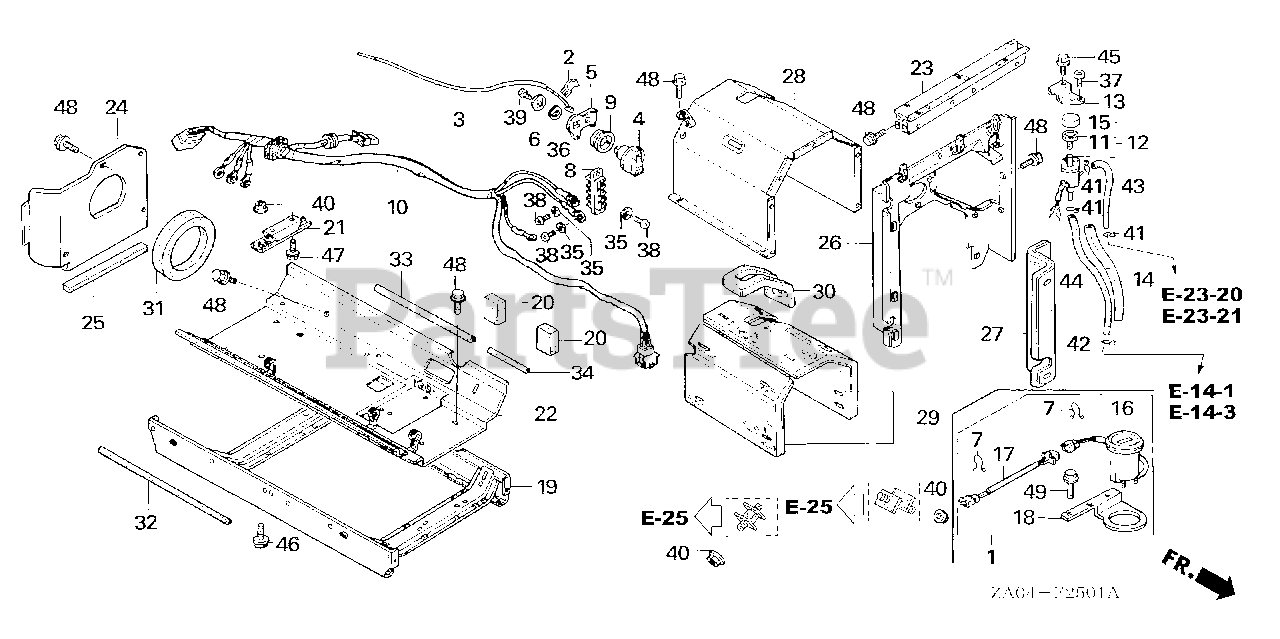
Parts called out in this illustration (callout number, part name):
1	METER KIT, HOUR
2	HOLDER, CONTROL CABLE
3	CABLE, CHOKE
4	KNOB, CHOKE CONTROL
5	ARM, CHOKE
6	WASHER, SPECIAL
7	CLIP, PURSE LOCK
8	TERMINAL, A.C. OUT
9	BUSH, PETCOCK SHAFT
10	WIRE HARNESS ASSY., A.C. (NOT AVAILABLE)
11	FILTER ASSY., SOLENOID VALVE
12	VALVE ASSY., CONTROL
13	STAY, IDLE CONTROL
14	PROTECTOR, TUBE (9X210)
15	CAP, AIR FILTER
16	METER ASSY., HOUR
17	CORD, HOUR METER CONNECTING
18	BRACKET, HOUR METER
19	FRAME (LOWER)
20	SEAL, FRAME (LOWER)
21	RUBBER, GENERATOR MOUNTING
22	COVER (LOWER)
23	BEAM, CENTER
24	COVER, RR. GENERATOR
25	SEAL, RR. GENERATOR COVER
27	INSULATOR, SEPARATOR
28	COVER, GENERATOR
29	INSULATOR, GENERATOR COVER
30	SEAL A, GENERATOR COVER
31	SEAL, GENERATOR END COVER
32	RUBBER A, COVER SEAL (LOWER)
33	RUBBER B, COVER SEAL (LOWER)
34	RUBBER C, COVER SEAL (LOWER)
35	WASHER, SPRING (6MM)
36	WASHER, WAVE (10MM)
37	SCREW, PAN (5X8)
38	SCREW, PAN (6X10)
39	SCREW, TAPPING (4X10)
40	NUT, FLANGE (10MM)
41	CLIP, TUBE (B7)
42	CLAMP, TUBE (D8)
43	BULK HOSE, VACUUM (3.5X1000) (3.5X170)
44	BULK HOSE, VACUUM (3.5X1000) (3.5X280)
45	BOLT, FLANGE (6X12)
46	BOLT, FLANGE (10X16)
47	BOLT, FLANGE (10X25)
48	BOLT, FLANGE (6X10)
49	BOLT, FLANGE (6X12)
